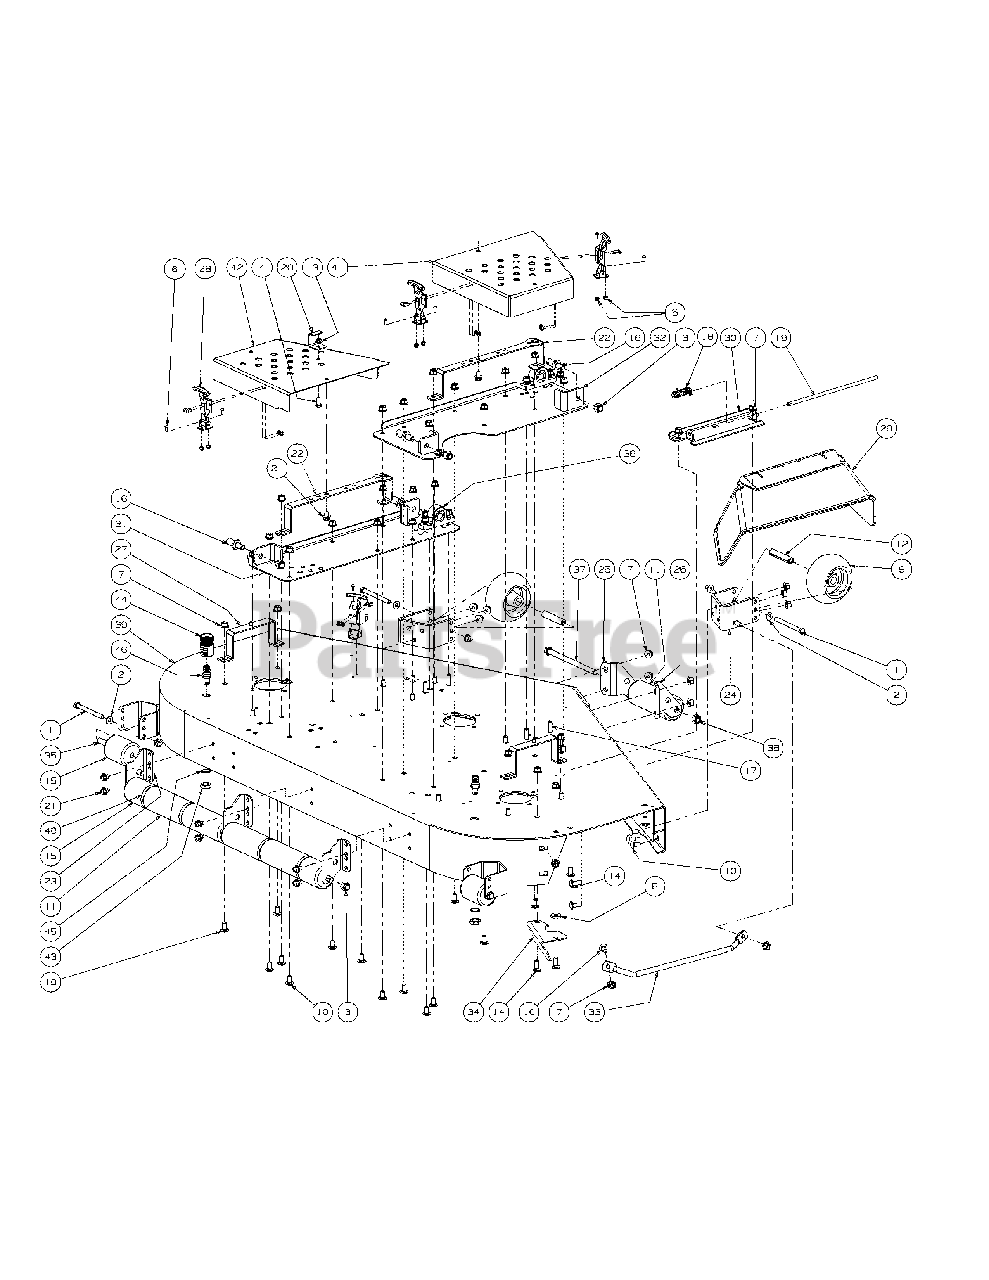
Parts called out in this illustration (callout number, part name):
1	Hex Cap Screw, 3/8-16, 3.75
2	Flat Washer, 3/8
3	Lock Nut, Nylon Insert, 1/2-13
4	Hex Cap Screw, 5/16-18 x .75
5	Lock Nut, Nylon Insert, 10-32
6	Phillips Head Screw, 10-32
7	Flange Lock Hex Nut, 3/8-16
8	Idler Washer
9	Complete Wheel, 5.00 Dia.
10	Carriage Bolt, 3/8-16 x .75 Lg.
11	Front Roller
12	Wheel Spacer
13	Nut, 5/16-18, Hex Flange Lock
14	Carriage Bolt, 3/8-16 x 1
15	Grass Catcher Roller
16	Pin, 5/8 Dia. x 1.2 Lg.
17	Carriage Screw, 3/8-16 x 1.25
18	Torsion Spring, 0.4ID x 2.16Lg
19	Chute Deflector Rod
20	Stop Bracket
21	Hex Index Washer Screw, 3/8-16, .5
22	Belt Cover Support
23	Deck Roller Mount Bracket
24	Anti-Scalp Wheel Front Mount Bracket
27	Outer Belt Cover Support Assembly
28	T-Handle Latch Draw
29	Chute Deflector
30	Chute Deflector Bracket
31	Left Hand Mount Deck Bracket Assembly
32	Right Hand Deck Bracket Assembly
33	Finger Guard
34	Chute Bracket
35	Spacer, .385 x .50 x 3.045
36	Pillow Block
37	Hex Cap Screw, 1/2-20 x 7.50
38	Lock Nut, Nylon Insert, 1/2-20
39	60 Deck Assembly
40	J-Hook w/ Threaded Roller
41	Right Hand Deck Belt Cover
42	Left Hand Deck Belt Cover
43	Hex Nut, M16-1.5
44	Water Nozzle Adaptor
45	Lock Washer, 17 x 23.8 x 1.95
46	Deck Water Nozzle
